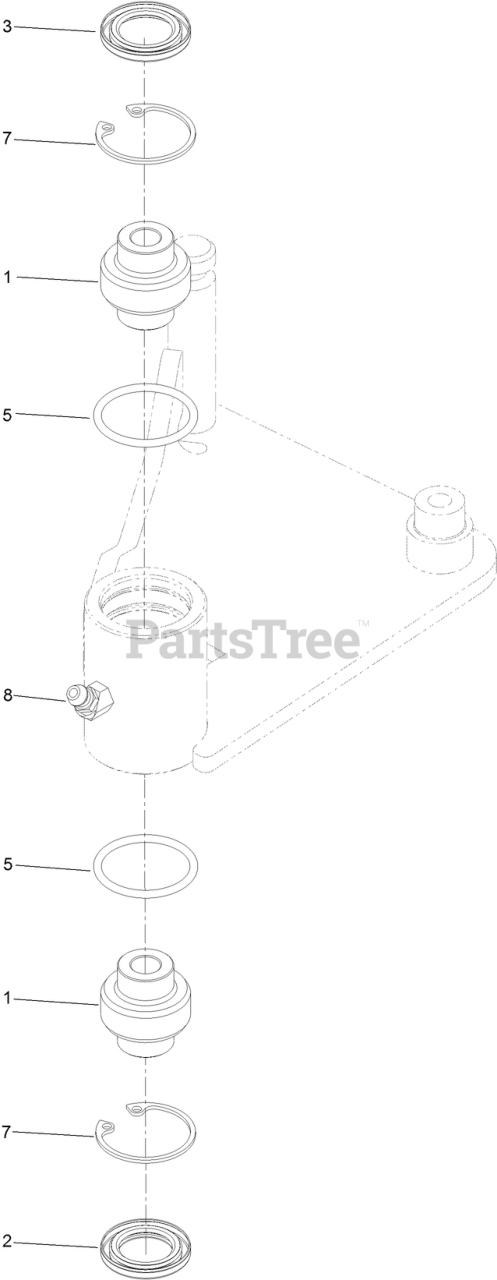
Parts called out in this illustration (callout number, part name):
1	BEARING-SPHERICAL
2	SEAL-LIP, DOUBLE
3	SEAL-LIP, SINGLE
5	O-RING
7	RING-SNAP
8	FITTING-LUBE, 45 DEG
